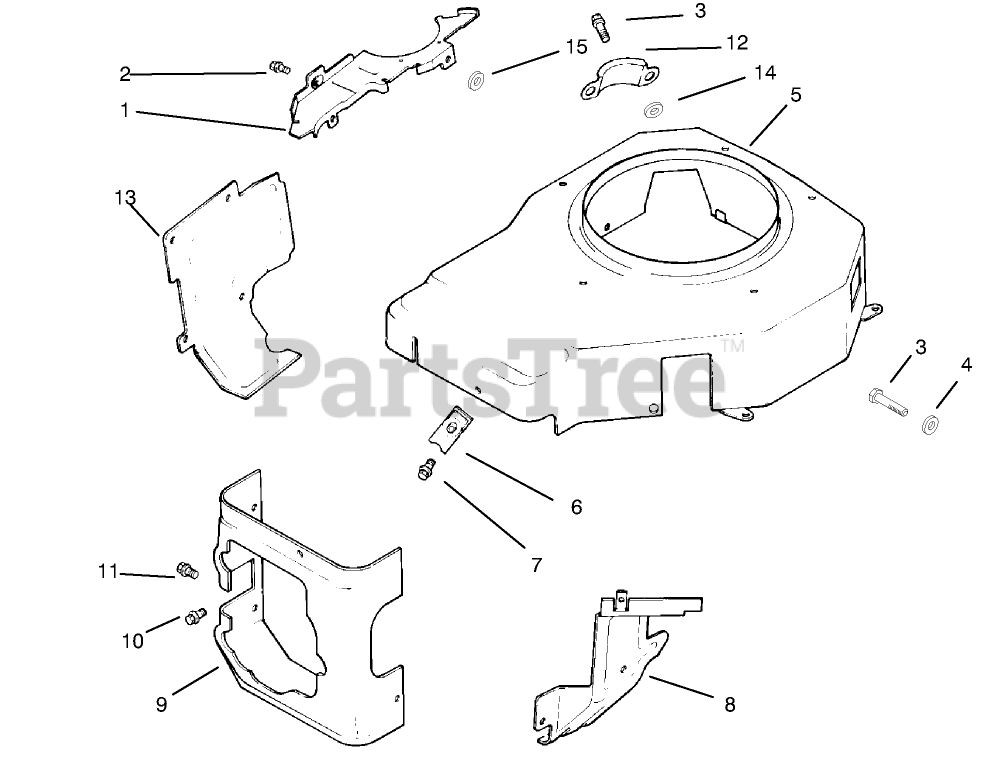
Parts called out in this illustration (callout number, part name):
1	Plate-Blower Housing (Only On: 72042,72043,72062,72063)
2	Screw
3	Screw
4	Washer
5	Housing-Blower
6	Clip
7	Screw
8	Baffle-Carburetor (Only On: 72042, 72043, 72062, 72063)
9	Baffle-Cylinder Head (Only On: 72042, 72063, 72062, 72043)
10	Screw
11	Screw
12	Cover-Pinion
13	Baffle-Cylinder Barrel (Only On: 72042, 72063, 72062, 72043)
14	Washer
15	Washer
